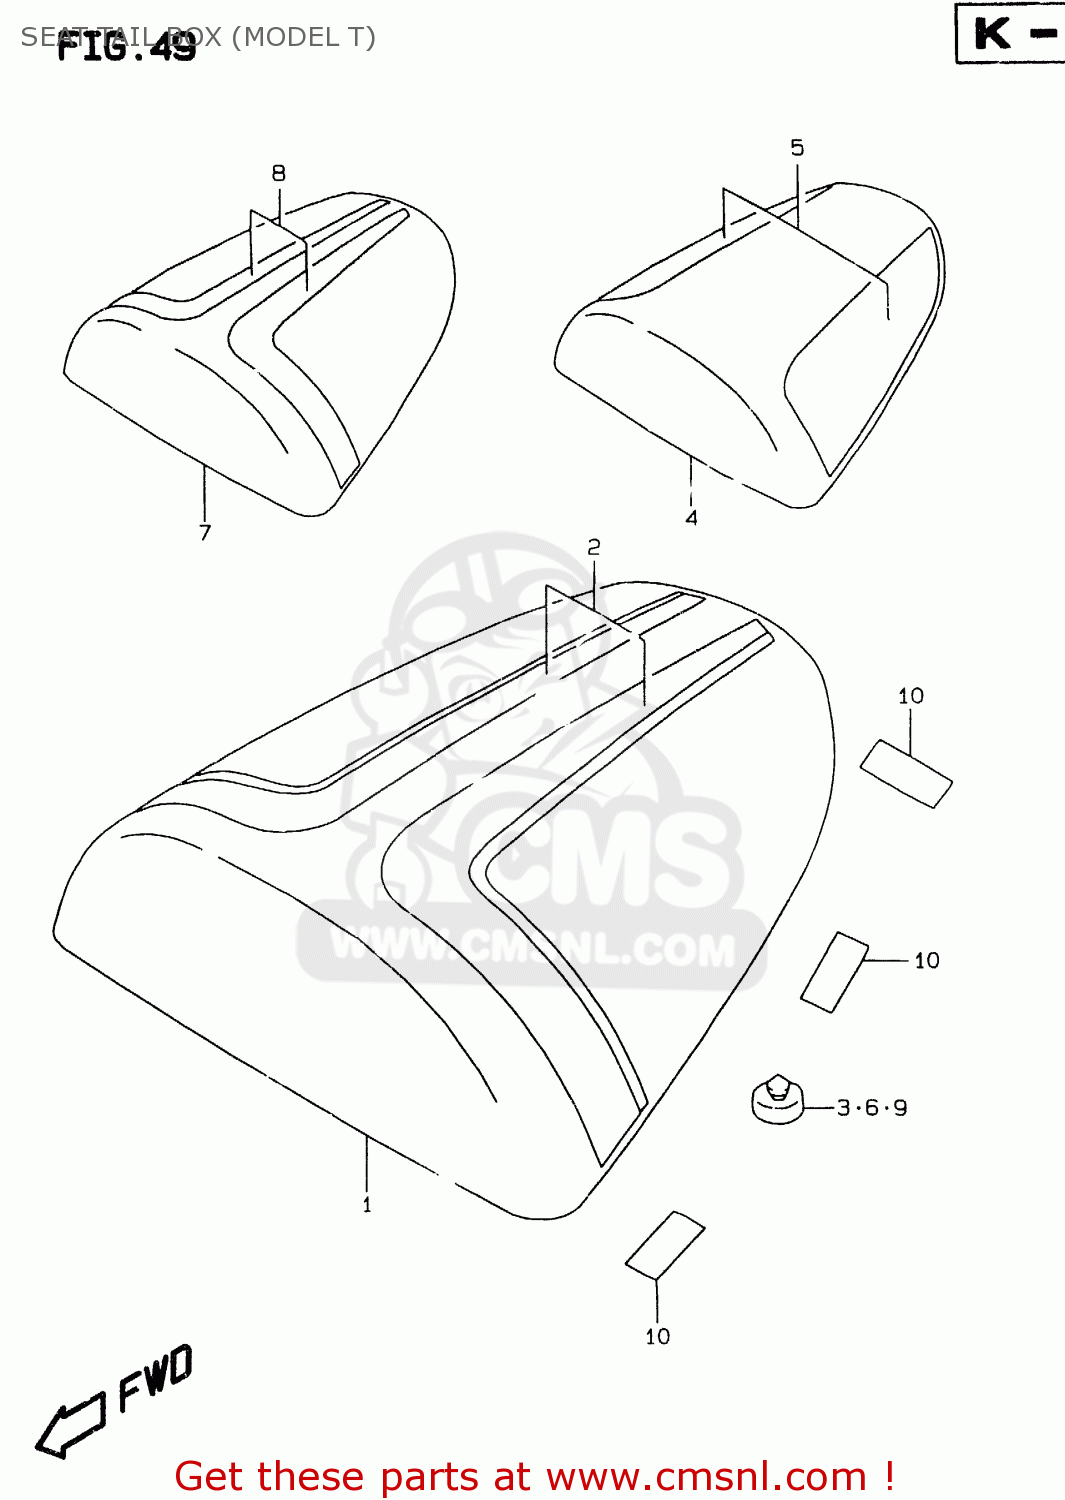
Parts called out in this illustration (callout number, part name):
1	BOX ASSY,SEAT TAIL(WHITE)
2	TAPE SET,BOX SEAT TAIL
3	CUSHION(11.5X22X20)
4	BOX ASSEMBLY,SEAT TAIL
5	TAPE SET,BOX SEAT TAIL
6	CUSHION(11.5X22X20)
7	BOX ASSY,SEAT TAIL(BROWN)
8	TAPE SET,BOX SEAT TAIL(YELLOW)
9	CUSHION(11.5X22X20)
10	PROTECTOR SET,SEAT TAIL BOX
